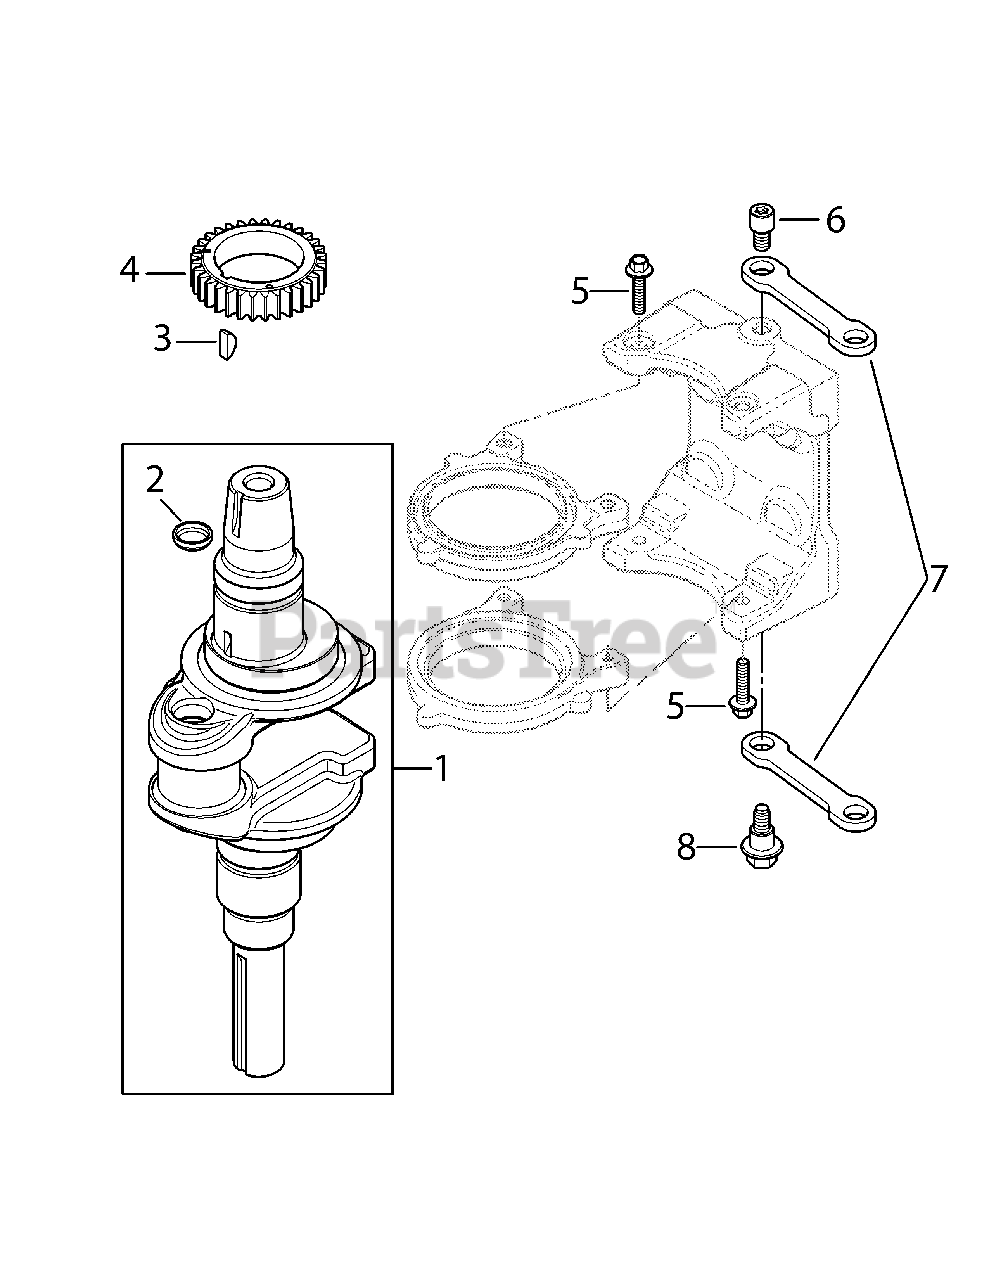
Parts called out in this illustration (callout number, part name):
1	Crankshaft Assembly Kit
3	Key, 3/16 X 5/8
4	Crankshaft Gear
5	Flange Screw, M6 X 1.0 X 25
6	Link Pivot Screw
7	Balance Weight Linkage
8	Shoulder Screw
